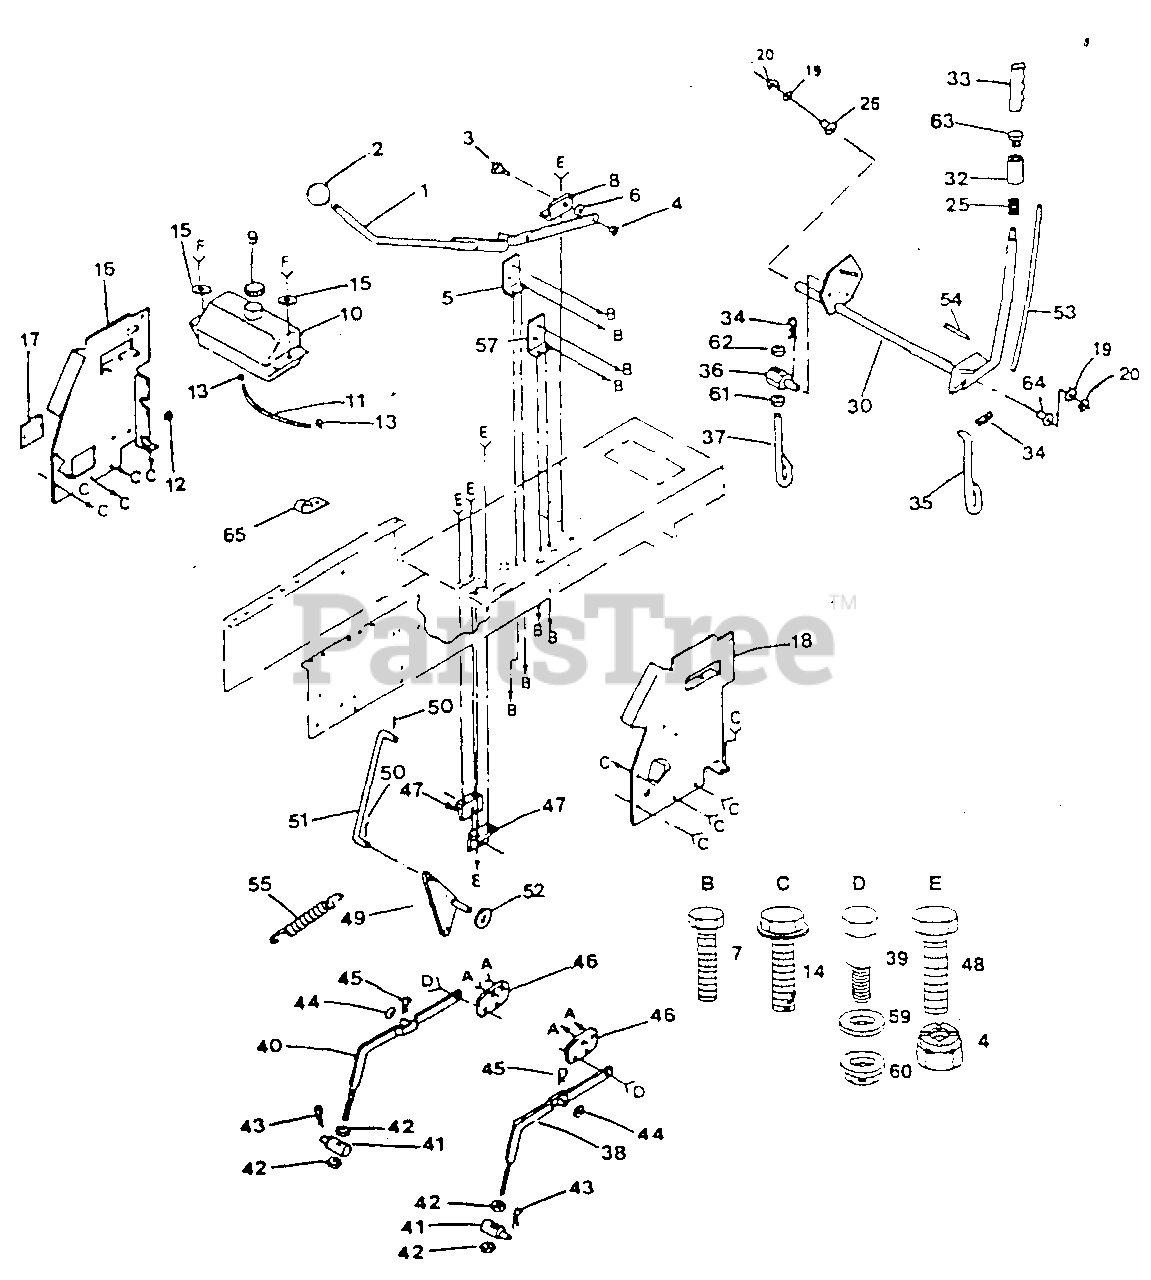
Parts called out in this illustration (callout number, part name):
1	Handle, Clutch, Mower (AYP part number)
2	Knob
3	Bolt, Shoulder
4	Nut, Crownlock 3/8-16
5	Bracket, Switch, Interlock
6	Washer 17/32 x 15/16 x 16 Ga.
7	Screw, Hex, Tapping, #10-24 x 1/2
8	Support, Lever, Clutch
9	Cap, Fuel (AYP part number)
10	Tank, Fuel (AYP part number)
11	Line, Fuel
12	Grommet
13	Clamp, Hose
14	Screw, Hex, Washer Head, Thread Rolling 3/8-16 x 3/4
15	Washer 13/32 x 1 x 12 Ga.
16	Panel, Dash, L.H.
17	Cover, Access
18	Panel, Dash, R.H. (AYP part number)
19	Washer 21/32 x 7/8 x 16 Ga. (AYP part number)
20	E-Ring (AYP part number)
25	Spring (AYP part number)
30	Shaft, Lift (AYP part number)
32	Plunger (AYP part number)
33	Grip, Handle
34	Retainer, Spring (AYP part number)
35	Link, Lift
36	Trunnion, Lift (AYP part number)
37	Link, Lift, Adjustable
38	Arm, Suspension, R.H.
39	Bolt, Shoulder 3/8-16
40	Arm, Suspension, L.H.
41	Trunnion, Lift, Lower (AYP part number)
42	Nut, Hex 1/2 - 13 (AYP part number)
43	Retainer, Spring
44	Washer 17/32 x 15/16 x 16 Ga.
45	Retainer, Spring
47	Bracket, Bellcrank
48	Bolt, Hex 3/8-16 x 3/4 (AYP part number)
49	Bellcrank Assembly
50	Pin, Cotter 1/8 x 3/4
51	Rod, Clutch, Primary (AYP part number)
52	Washer 13/32 x 7/8 x 10 Ga.
53	Rod, Lever, Lift (AYP part number)
54	Pin, Groove
55	Spring, Extension (AYP part number)
57	Bracket, Switch
59	Washer, Spring
60	Locknut, Flange 3/8-16 (AYP part number)
61	Nut, Hex Jam 7/16-20
62	Nut, Crownlock 7/16-20
63	Button, Plunger (AYP part number)
64	Bearing, Nylon
65	Clip, Insulated
